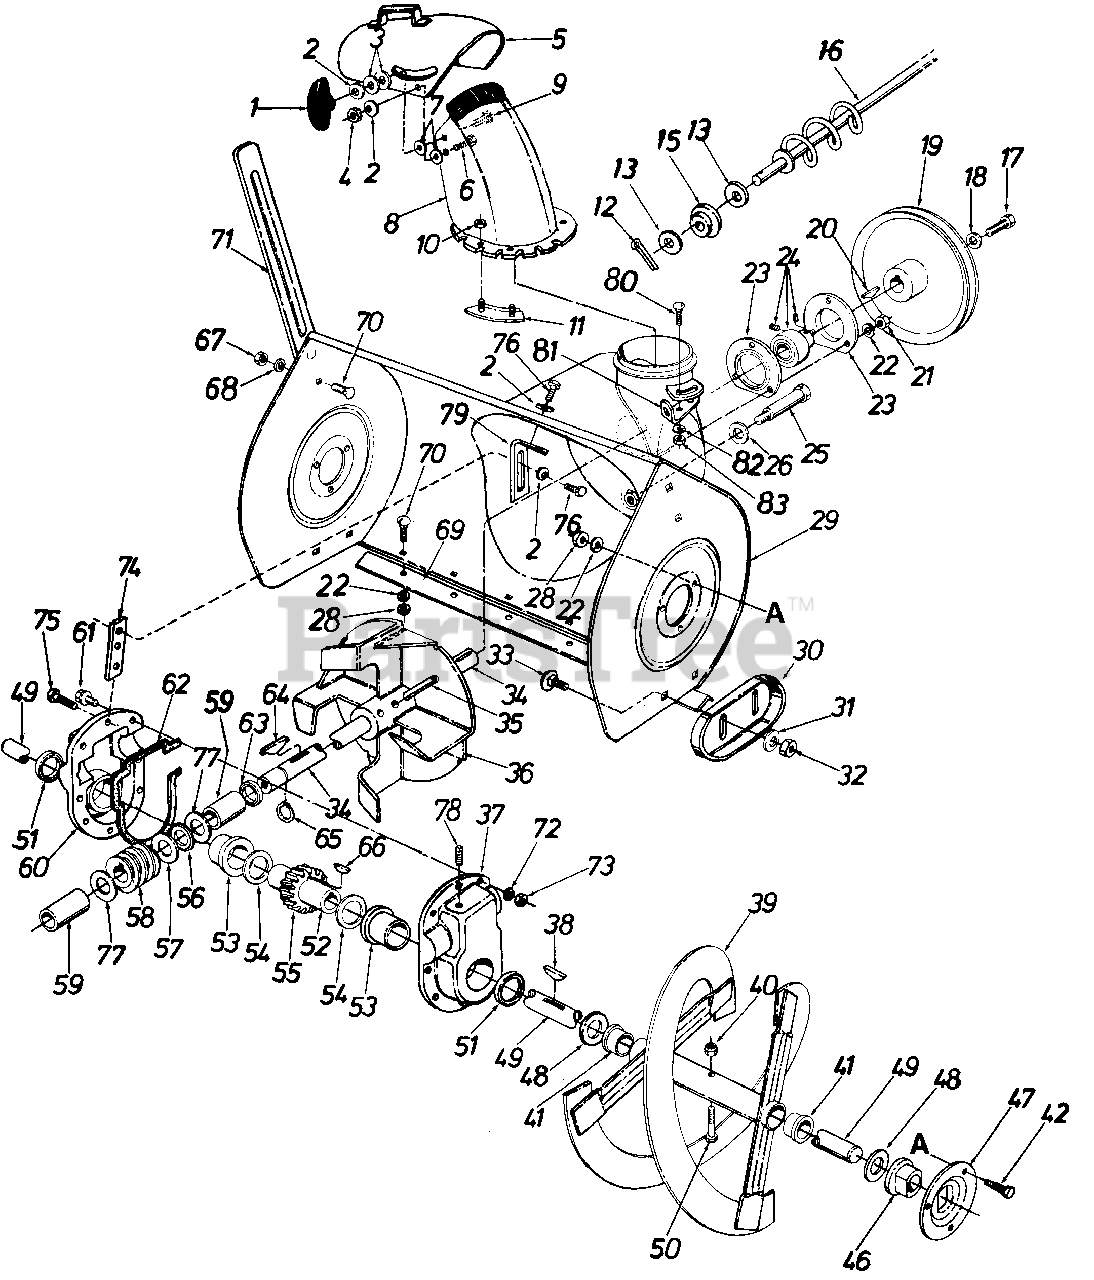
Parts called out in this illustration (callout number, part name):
1	Hand Knob Ass'y.
2	Bell-Wash. .345 I.D. x .88 O.D. x .060
3	Fl. Wash. .312 I.D. x 1.125 O.D. x .125
4	Hex Cent. L-Nut 5/16-18 Thd.
5	Top Chute Ass'y.
6	Carr. Bolt 5/16-18 x .62" Lg.
7	Fl-Wash. .53 I.D. x 1.25 O.D. x .100
8	Chute Ass'y.
9	Carr. Bolt 5/16-18 x 1.00" Lg.
10	Hex Cent. L-Nut '/2-20 Thd.
11	Chute Flange Keeper Ass'y.
12	Cotter Pin
13	Fl-Wash. .385" I.D. x .62" O.D.
15	Bushing
16	Chute Crank Ass'y.
17	Hex L-Scr. 5/16-18 x .88" Lg.
18	Bell-Wash. .345 I.D. x .88 O.D. x .060
19	V-Pulley .875 I.D. x 10.12 O.D.
20	#9 Hi-Pro Key 3/16 x 3/4" Dia.
21	Hex Nut 5/16-18 Thd.
22	L-Wash. 5/16" Scr.
23	Bearing Hsg.-Self Aligning Brg.
24	Self Aligning Brg. .875 I.D.
25	Stud 3/8-16 x 2.75" Lg.
26	Bell-Wash. .400 I.D. x .88 O.D. x .060
28	Hex Nut 5/16-18 Thd.
29	Blower Hsg. Ass'y.
30	Slide Shoe
31	Bell-Wash. .400 I.D. x .88 O.D. x .060
32	Hex Jam Nut 3/8-16 Thd.
33	Carr. Bolt 3/8-16 x .62" Lg.
34	Blower Axle
35	Spring Pin Spiral 5/16" Dia. x 1.75" Lg.
38	#91 Woodruff Key 1/4" x 3/4" Dia.
40	Hex Ins. L-Nut 5/16-18 Thd.
41	Plastic Bushing
42	Hex Sems Scr. 5/16-18 x .75" Lg.
46	Flange Brg. w/Flats 1.0" I.D.
47	Bearing Hsg.-Spiral Hsg.
48	Fl-Wash. 1.06 I.D. x 1.75" O.D. x .100
49	Spiral Axle-26"
50	Hex Bolt 5/16-18 x 1.75" Lg.
51	Oil Seal 1.50" I.D.
52	Worm Gear Shaft
53	Flange Brg. 1.503 I.D.
54	Fl-Wash. 1.50 I.D. x 2.00 O.D. x .030
55	Double Threaded Worm Gear
56	Thrust Brg. .88 I.D. x 1.44 O.D. x .078
57	Fl-Wash. .88 I.D. x 1.40 O.D. x .150
58	Double Threaded Worm-L.H.
59	Sleeve Brg. .875 I.D.
60	Complete Gear Hsg. Half-R.H.
61	Hex Scr. 5/16-18 x 1.00" Lg.
62	Gasket
63	Oil Seal .875" I.D.
64	#9 Hi-Pro Key 3/16 x 3/4" Dia.
65	Snap Ring for .875" Dia. Shaft
66	#91 Woodruff Key 1/4 x 3/4" Dia.
67	Hex Nut 5/16-18 Thd.
68	L-Wash. 5/16" Scr.
70	Carr. Bolt 5/16-18 x .62" Lg.
71	Drift Cutter
72	Wave Wash. 5/16" Scr.
73	Hex Ins. L-Nut 5/16-18 Thd.
74	Gear Hsg. Support Plate
75	Hex Scr. 5/16-18 x 1.25" Lg.
76	Hex Wash. Hd. Self-Tap Scr. 5/16-18 x .75" Lg.
77	Fl-Wash. .88 I.D. x 1.40 O.D. x . 1 50
78	Filler Plug
80	Carr. Bolt 5/16-18 x .75" Lg.
82	Bell-Wash. .345 I.D. x .88" O.D.
83	Hex Nut 5/16-18 Thd.
